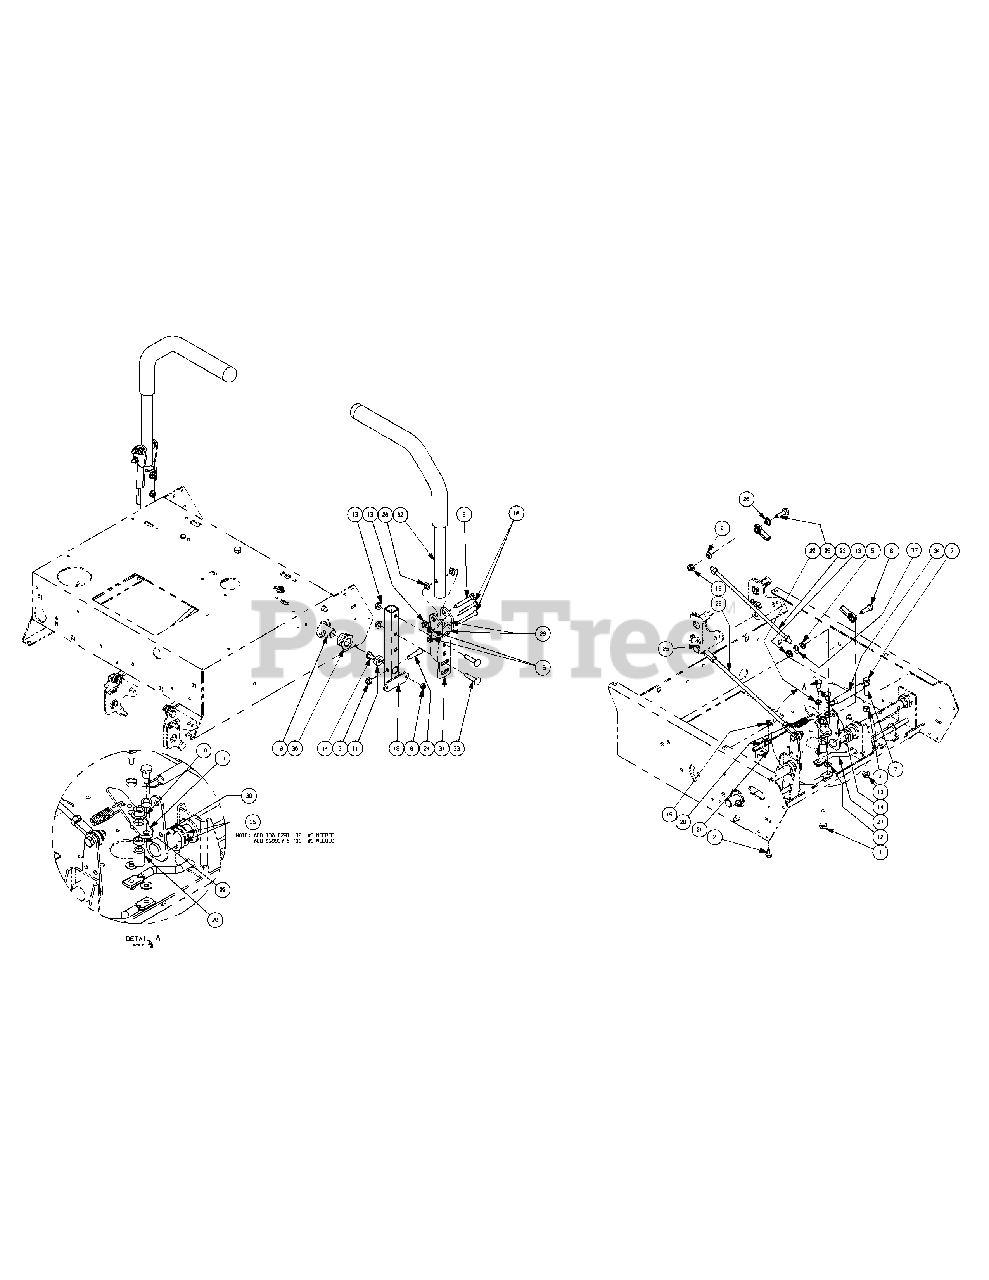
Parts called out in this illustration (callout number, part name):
1	Hex Cap Screw, 3/8-16 x 1-1/2
2	Hex Cap Screw, 1/4-20 x 1/2
3	Nylock Nut, 5/16-18
4	Hex Nut, 5/16-18
5	Flat Washer, 5/16
6	Hex Head Cap Screw, 5/16-18 x 1.00
7	Hex Cap Screw, 5/16-18 x 1-1/2
8	Hex Cap Screw, 5/16-18 x 2.00
9	Nut, 1/4-28, SS, Nylon Insert
10	Nut, Flange Lock, 3/8-16
11	Control Rod Spacer
12	Flat Washer, 1.4 x .630 x .0515
13	Nut, 5/16-18, Lock
14	Shoulder Screw, 1/4-28
15	Nut, 1/4-20, Hex Flange Lock Nut
16	Hex Cap Screw, 1/4-20 x 2.00
17	Brake Lever Plate
20	Spacer, .385 ID x .625 OD x .869
21	Brake Cable Mounting Bracket
22	Spacer, .380 x .563 x .196
23	Steering Link Rod
24	Socket Head Capscrew, 5/16-18 x 1.25
25	HHCS, 5/16-18 x 1-1/4
26	Bushing, .310 x .172 x .688 x .06
27	Control Lock Rod
28	Control Cable Lock Out
29	Spacer, .25 ID x .38 OD x 1.13
30	Retainer Ring, E-Clip
32	Control Handle Pivot Tube
32	Grip, 1.0
33	Carriage Bolt, 5/16-18 x 1.50
34	Extension Spring, .53 OD x 4.7
35	Flat Washer, .793 ID x 1.24 OD x .060
36	Hex Flange Bearing, .752 ID
37	Push Retainer
